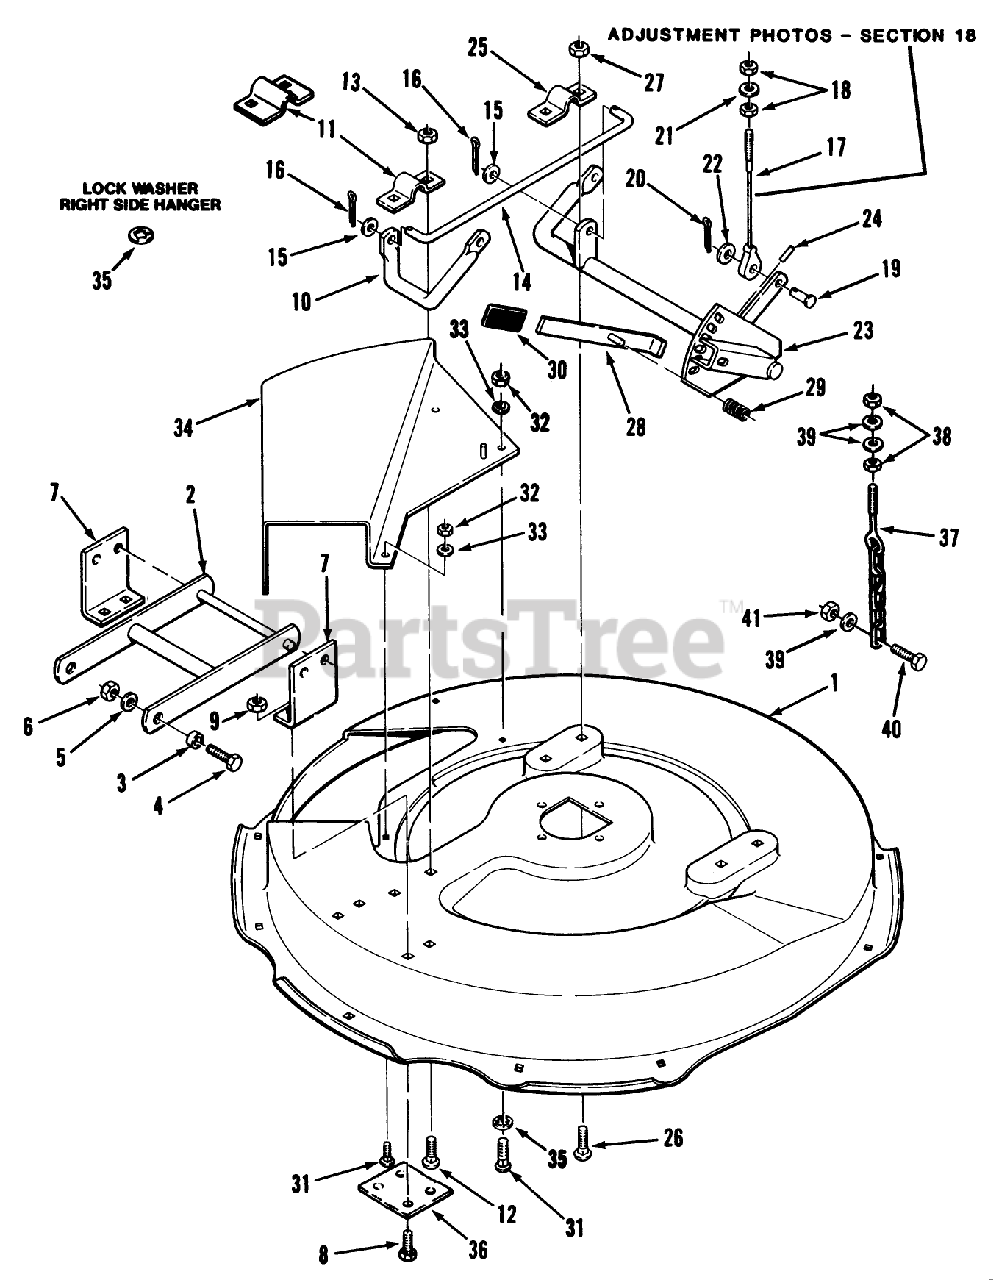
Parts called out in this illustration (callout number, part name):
3	SPACER
7	BRKT FRONT MOWER *R
11	CLAMP
17	CABLE MOWER SUPPORT
21	WASHER 5/16 SAE
24	SPIROL PIN
25	CLAMP
28	LEVER ASSY
29	SPRING-COMPRESSION
39	WASHER 5/16 SAE
